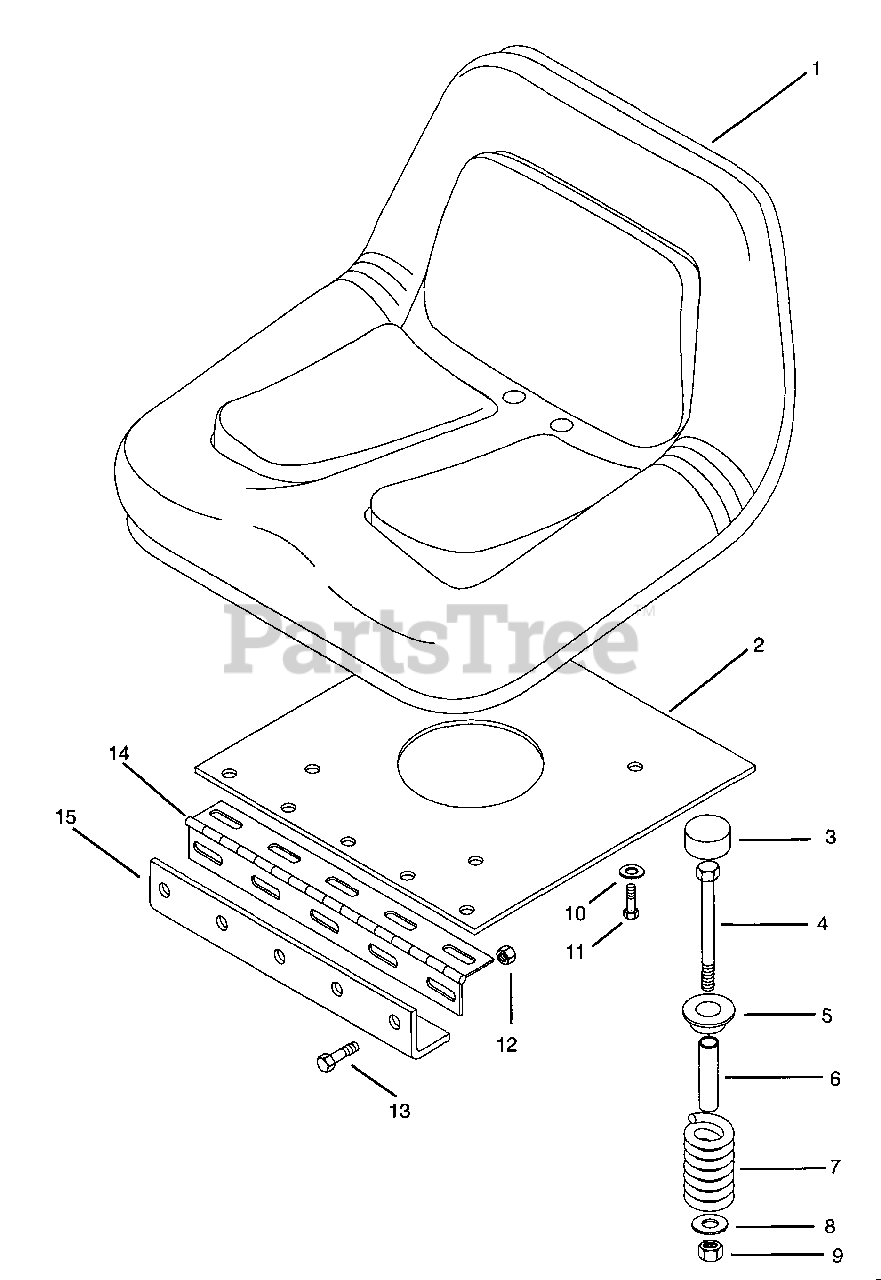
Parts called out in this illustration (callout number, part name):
1	Seat High Back
2	Plate, Seat Mounting
3	Molded Cap 1.5 OD, 1.0 ID
4	Bolt-Hex .25-20 x 2.25
5	Cap, Valve Spring
6	Bushing, Split Rolled
7	Spring-Compression .149 x 1.095 x 1.75
8	Washer-Flat-Steel .344 x .688 x .065
9	Nut-Locking-Nylon .250-20 Grade 2
10	Washer-Lock .313 x .078
11	Bolt-Hex .31-18 x .625
12	Nut-Locking-Nylon .312-18 Grade 2
13	Bolt-Hex .31-18 x .625
14	Hinge
15	Bracket, Seat Support
